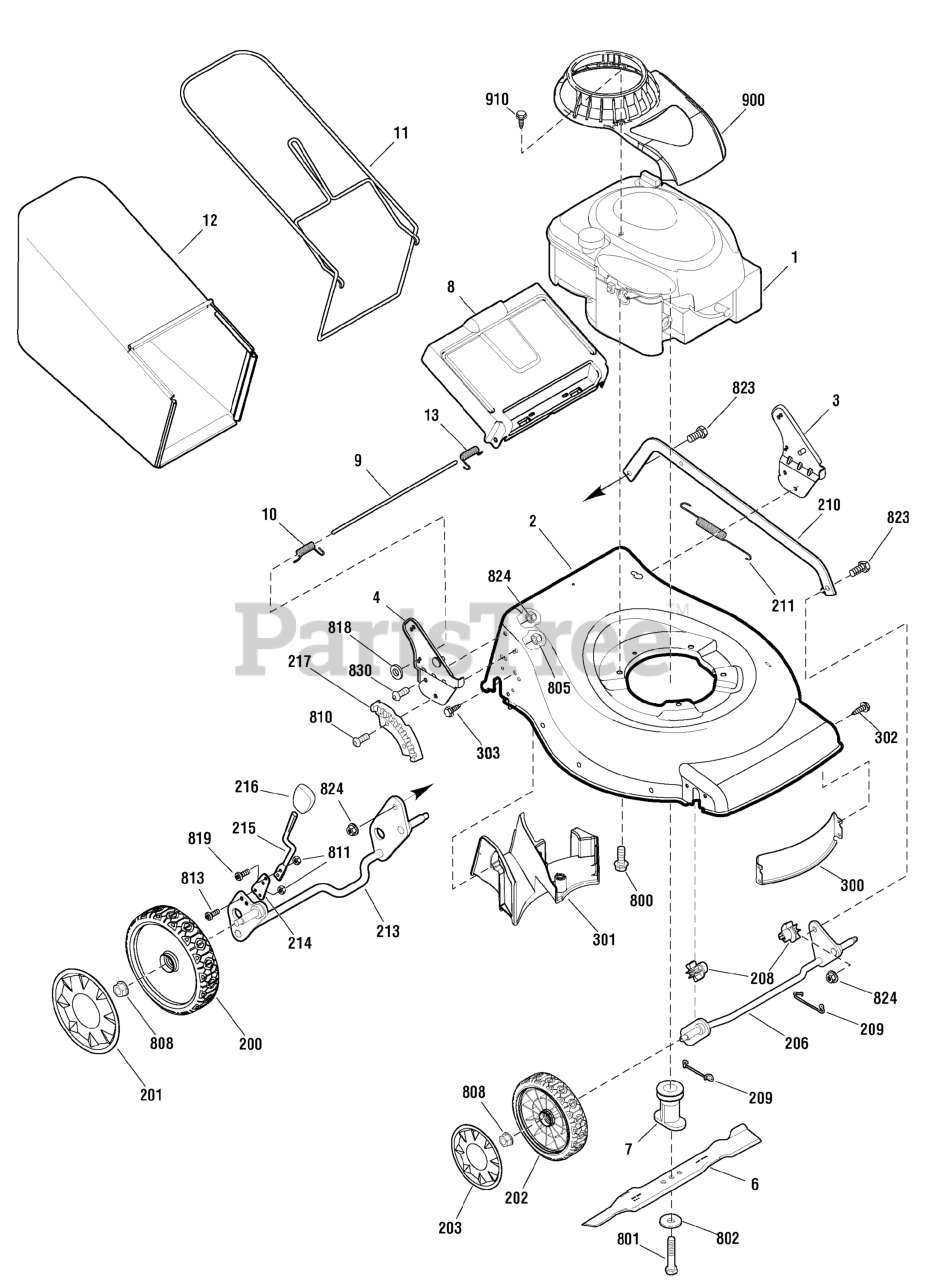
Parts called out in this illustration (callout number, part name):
1	* ENGINE, 4.5GT Briggs & Stratton
2	MOWER HOUSING
3	BRACKET ASSEMBLY, Left Handle
4	BRACKET ASSEMBLY, Right Handle
6	BLADE, 16 in
7	BLADE ADAPTER ASSEMBLY
8	DOOR, Rear
9	ROD, Rear Door
10	SPRING, Torsion Rear Door, Right
11	FRAME ASSEMBLY
12	BAG ASSEMBLY
13	SPRING, Torsion Rear Door, Left
200	WHEEL, Rear
201	HUBCAP, Rear
202	WHEEL, Front
203	HUBCAP, Front
206	CROSSBAR ASSEMBLY, Front
208	BUSHING, Front Crossbar
209	SPRING, Clip Crossbar
210	LINK, Single Lever
211	SPRING, Extension
213	REAR CROSSBAR
214	SPRING, Adjuster
215	LEVER, Height Adjustment
216	KNOB, Adjuster
217	BRACKET, Height Adjuster
300	BAFFLE, FRONT, 16"
301	BAFFLE, REAR, 16"
302	SCREW, Pan Head, Taptite, 1/4-20 x 1/2
303	SCREW, Pan Head, 1/4-15 x 5/8
800	CAPSCREW, Hex Head, 3/8-16 x 1
801	BOLT, Blade, 3/8-24 x 2
802	WASHER, Belleville
805	NUT, Nylock, M8 x 1-1/4
808	NUT, Flange, 3/8-16
810	BOLT, Hex Key Head
811	NUT, Nylock
813	SCREW, Torx Head, M5 x .8 x 14mm
818	PUSHNUT, 1/4
819	SCREW, Torx Head, M5 x .8 x 12.5mm
823	BOLT, Shoulder, 5/16-18 x 1
824	NUT, Flange, 5/16-18
830	CAPSCREW , 5/16-18 x 3/4
900	SHROUD
910	CAPSCREW, Hex Washer Head
1000	DECAL KIT
